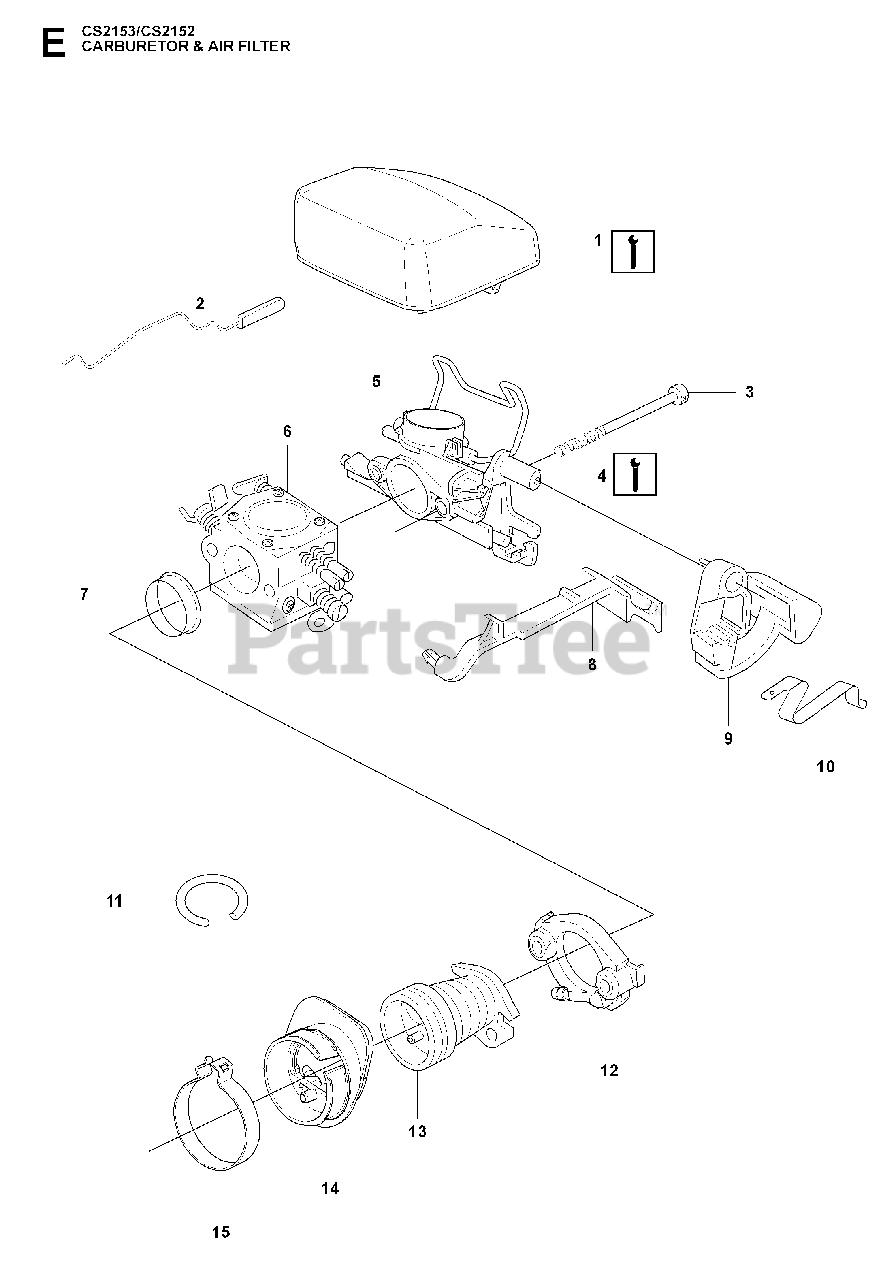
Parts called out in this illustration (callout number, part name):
1	AIR FILTER - NYLON (B)
1	AIR FILTER - NYLON (Y)
1	AIR FILTER - FELT
2	THROTTLE ROD
4	INLET ELBOW
5	FILTER CLAMP
6	CARBURETOR
8	CHOKE CONTROL
11	HOSE, IMPULSE
14	PARTITION
15	CLAMP, INTAKE
